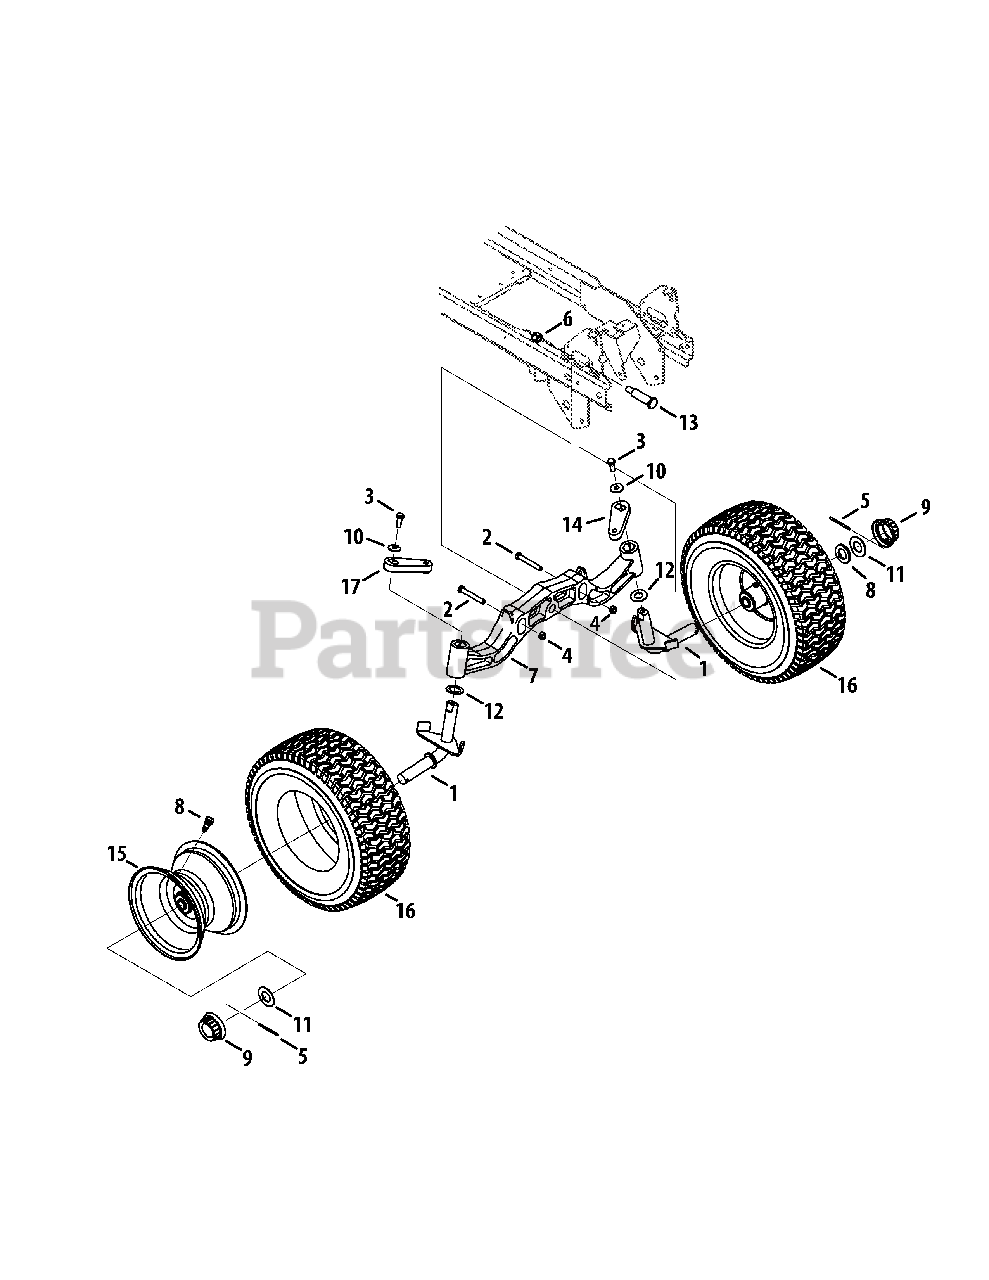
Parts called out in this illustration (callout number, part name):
1	Axle Assembly, 3/4
2	Hex Screw, 3/8-16 x 2.75
3	Hex Cap Screw, 3/8-24 x 1.00
4	Hex Lock Nut, 3/8-16
5	Cotter Pin, 3/16 x 2.0
6	Hex Lock Nut, 1/2-13
7	Pivot Bar
8	Tubeless Air Valve
10	Bevel Washer, .390 x 1.130 x .062
11	Flat Washer, 1.05 x 1.92 x .06
12	Thrust Washer, 1.010 x 2.50 x .060
13	Shoulder Screw, .750 x 2.23
14	Steering Arm, LH
15	Rim Assembly, 16.0 x 6.5 x 8
16	Tire, 16.0 x 6.50-8.00
17	Steering Arm, RH
